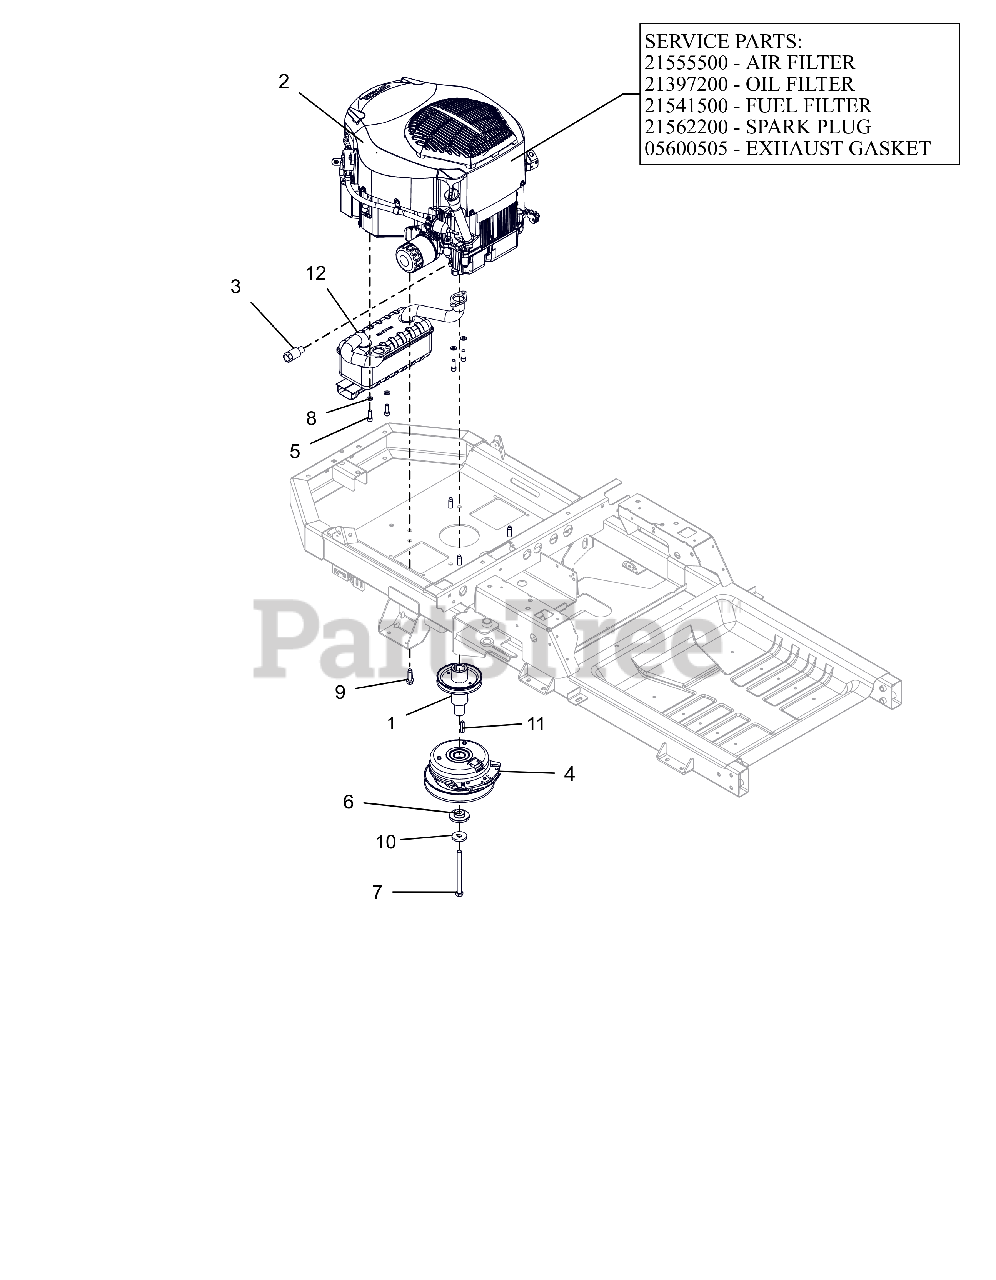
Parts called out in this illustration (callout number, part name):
1	WLDMT, DRIVE SHEAVE (LG XL)CZC
2	ENGINE, KOHLER TWIN - 25HP
2	AIR CLEANER, KOHLER
2	FILTER, OIL - KOH CV20
2	FILTER, FUEL
2	PLUG, SPARK (RFI)
2	GASKET, MUFFLER COURAGE TWIN
3	DRAIN, OIL
4	CLUTCH,105FTLB MONOPOLE 6.83"
5	SCR-CAP .31-18X.88 S/HD G8 ZCC
6	BSHG-FLG .469X1.06X.574X2.0
7	BLT-HEX.438-20X5 GR8 YZ NYTORQ
8	WSHR,LK-REG .312X.078 ZCC
9	SCR,TAP .375-16X1.25HWH TR ZCC
10	WASHER, 7/16" SPRING DISK
11	KEY-SQ .25 X 1.25 X .25 SAE
12	MUFFLER, KOHLER
